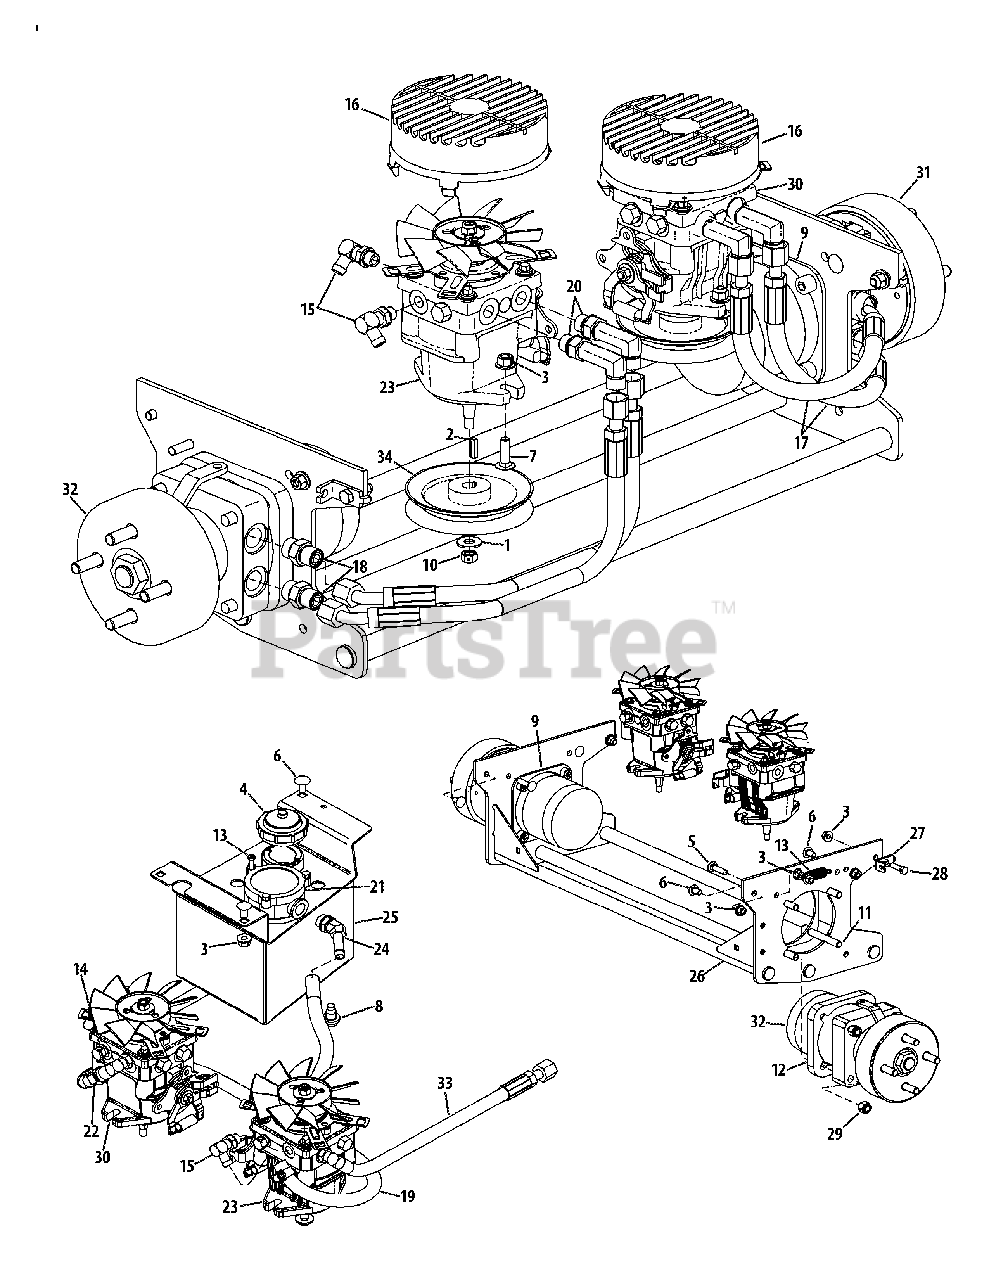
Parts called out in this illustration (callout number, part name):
1	Washer, .438 x 1.00 x .078
2	Key, .188 x .188 x .875
3	Flange Counter Lock Nut, 3/8-16
4	Hydro Oil Tank Cap
5	Carriage Bolt, 3/8-16 x 1.50
6	Carriage Bolt, 3/8-16 x .75
7	Carriage Bolt, 3/8-16 x 1.25
8	Oil Drain Plug, w/ Seal
9	Motor Back-Up Plate
10	Counter Lock Nut, 3/8-24
11	Socket Cap Screw, 1/2-13 x 3.50
12	Hydro Wheel Motor Spacer
13	Extension Spring, .74 x 2.7 x .075
14	Socket Cap Screw, 1/4-20 x .750
15	Elbow Fitting, 9/16 x 1/2
16	Pump Fan Shroud
17	Pump Moter Hose Assembly
18	Hydro Adapter, 8 x 10
19	Pilot Hydro Hose Assembly
20	Elbow Hydro Adapter, 8 x 8
21	Hydro Filter
22	Hose Clamp
23	RH Hydro Pump
24	Fitting, 3/4 x 1/2
25	Hydro Tank Assembly
26	Wide Motor Frame
27	Brake Cable Bracket
28	Hex Screw, 3/8-16 x 1.25
29	Hex Lock Nut, 1/2-13
30	LH Hydro Pump
31	LH Hydro Motor w/ Brake
32	RH Hydro Motor w/ Brake
33	Hose Assy. (Wheel Pump-Manifold)
